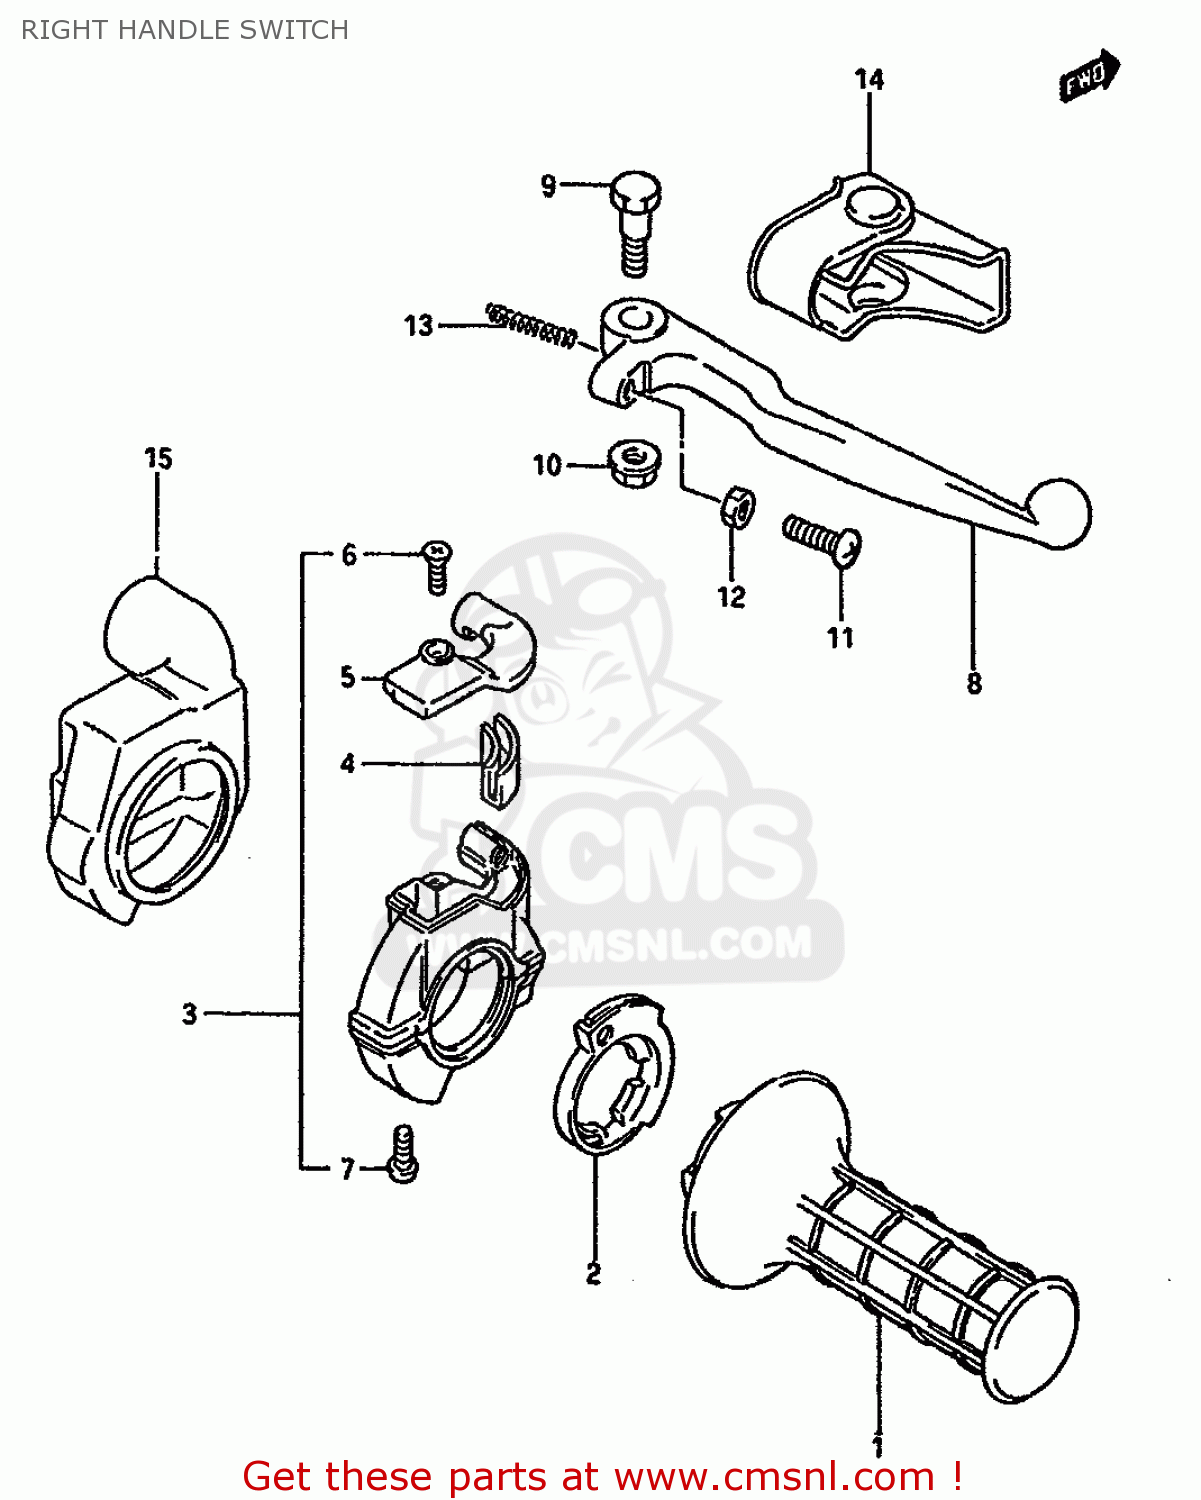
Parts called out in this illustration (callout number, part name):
1	GRIP,THROTTLE
2	ROTOR,THROTTLE GRIP
3	CASE ASSY,THROTTLE
4	GUIDE PIECE,THROTTLE
5	COVER,THROTTLE CASE
6	SCREW
7	SCREW
8	LEVER,BRAKE
9	BOLT,BRAKE LEVER
10	NUT,BRAKE LEVER
11	BOLT,ADJUST
12	NUT ,5MM
13	SPRING,RETURN
14	COVER,BRAKE LEVER
15	COVER,THROTTLE CASE
